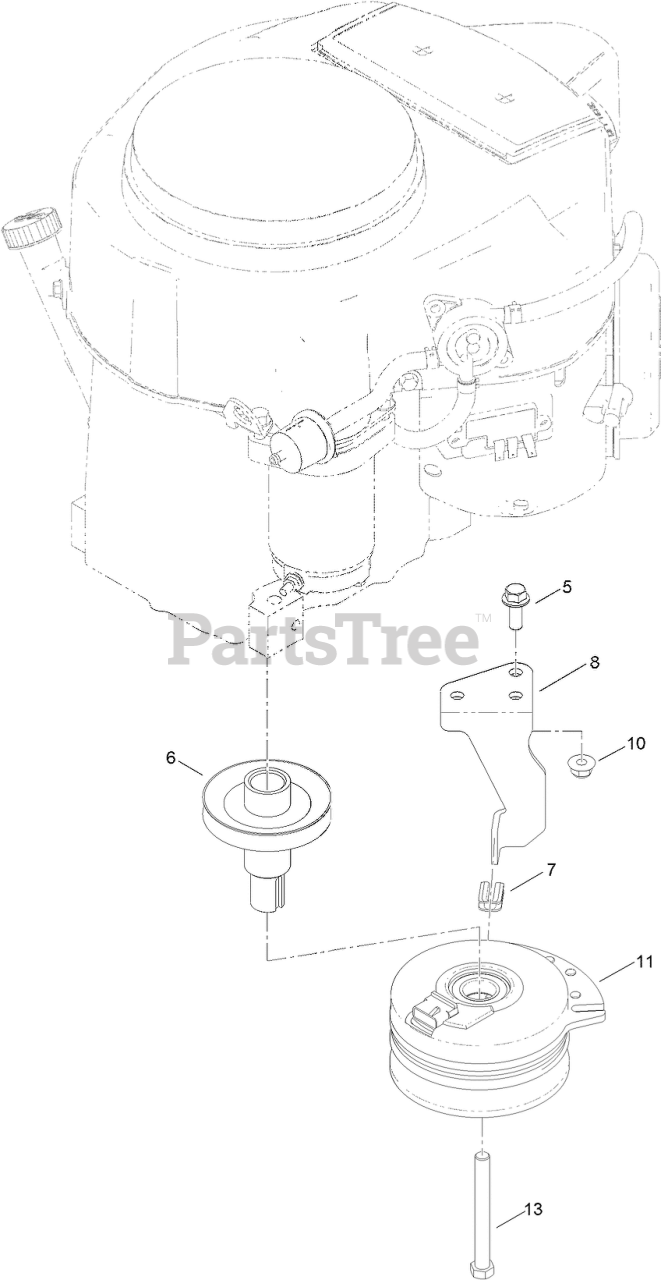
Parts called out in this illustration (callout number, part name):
5	SCREW-HHF
6	PULLEY-ENGINE
7	ISOLATOR-CLUTCH
8	STOP-CLUTCH
10	NUT-HF, NI
11	CLUTCH-ELECTRIC
13	SCREW-HH
